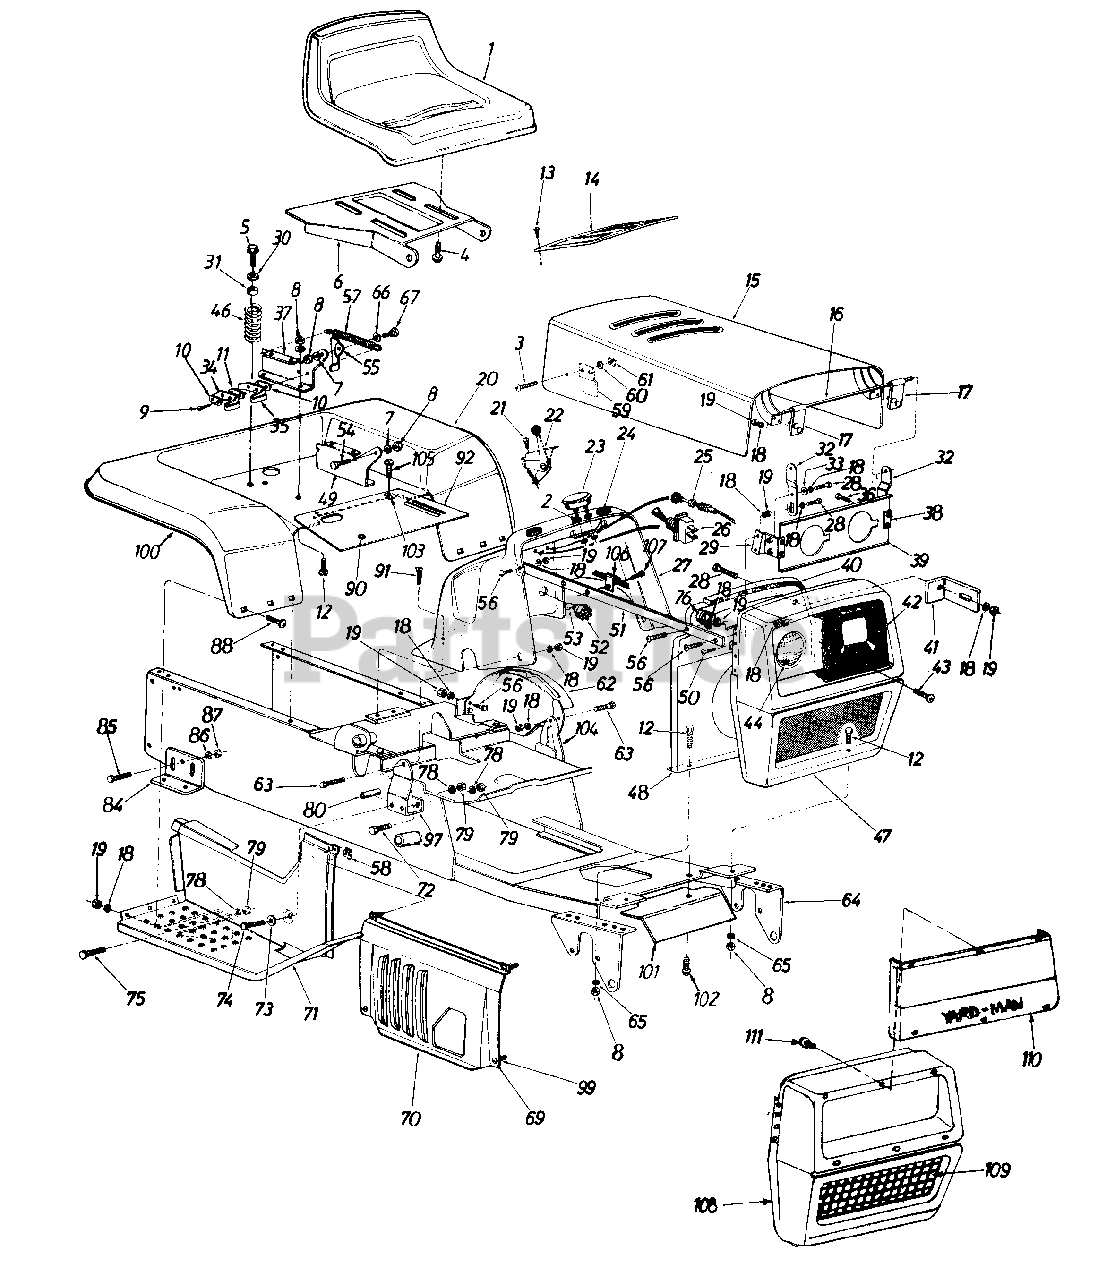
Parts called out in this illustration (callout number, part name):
1	Seat Ass'y. (Black)
2	L-Wash. .190" I.D.
3	Truss Hd. Mach. Scr. #10-24 x .38" Lg.
4	Hex Wash. Hd. Self-Tap Scr. 3/8-16 x .75" Lg.
5	Hex Wash. Hd. Tap Scr. 5/16-18 x .75" Lg.
7	L-Wash. 5/16" I.D.
8	Hex Nut 5/16-18 Thd.
9	Hex Wash. Hd. AB-Tap Scr. #8 x .5" Lg.
10	Insulator Plate
11	Insulator Boss Plate
12	Hex Bolt 5/16-18 x .75" Lg.
13	Self-Tap Oval Hd. Scr. 1/2" Lg.
14	Dash Panel Cover
15	Hood Ass'y.
16	Hinge Rod
17	Hood Hinge Ass'y.
18	L-Wash. 1/4" I.D.
19	Hex Nut 1/4-20 Thd.
20	Rear Fender
22	Throttle Control
23	Ammeter
24	Rubber Bumper
25	Choke Control
26	Light Switch
27	Dash Panel
28	Hex Bolt 1/4-20 x .62" Lg.
29	Hood support Brkt. Ass'y.-R.H.
30	Fl-Wash. .344" I.D. x .875"
31	Bushing
34	Safety Switch (Seat)
35	Safety Switch (Seat)
36	Hex Bolt 1/4-20 x .38" Lg.
38	Hood Support Brkt. Ass'y.-L.H.
41	Heat Shield Brkt.
42	Head Lamp Bezel
43	Truss Mach. Scr. #10-24 x .50" Lg.
44	Head Lamp
46	Compression Spring 4.5" Lg.
50	Truss Mach. Scr. 1/4-20 x .75" Lg.
51	Grille Strap
52	Ignition Switch
53	Ignition Key
54	shld. Bolt .437" Dia. x .162"
55	Seat Lift Bracket
56	Hex Bolt 1/4-20 x .75" Lg.
57	Extension Spring 5.31" Lg.
59	Hood Spring
60	L-Wash. #10
61	Hex Nut #10-24 Thd.
62	Speed Control Guide
63	Truss Mach. Scr. 1/4-20 x .75" Lg.
64	Frame Ass'y.
65	Bell-Wash. 5/16" I.D.
66	Spr. Wash. .445" I.D. x .75"
67	Shld. Bolt .437" Dia. x .268"
69	1/4-Turn Stud
73	Fl-Wash. .385" I.D. x .62" O.D.
74	Hex Bolt 3/8-16 x 3.00" Lg.
75	Hex Bolt 3/8-16 x 1.00" Lg. Grade 5
76	Snap Bushing
78	L-Wash. 3/8" I.D.
79	Hex Nut 3/8-16 Thd.
80	Spacer .375" I.D. x .62" O.D. x 2.00" Lg.
84	Transaxle Support Brkt.
85	Rd. Hd. Rib Neck Scr. 3/8-24
86	L-Wash. 3/8" I.D.
87	Hex Nut 3/8-24 Thd. (Gr. 5)
88	carr. Bolt 1/4-20 x .50" Lg.
90	Snap Bushing
91	Fl-Hd. Self-Tap Scr. 1/4-20 x .62" Lg.
100	Trim Strip 84" Lg.
103	Speed Nut #10-24 Thd.
104	Dash Panel Mtg. Brkt.-L.H.
105	Truss Mach. Scr. #10-24 x .5" Lg.
106	Clamp
107	Self-Tap Scr. 5/16 x .5" Lg.
110	Headlight Bezel
111	Hex Wash. Hd. Scr. #8 x .5" Lg.
